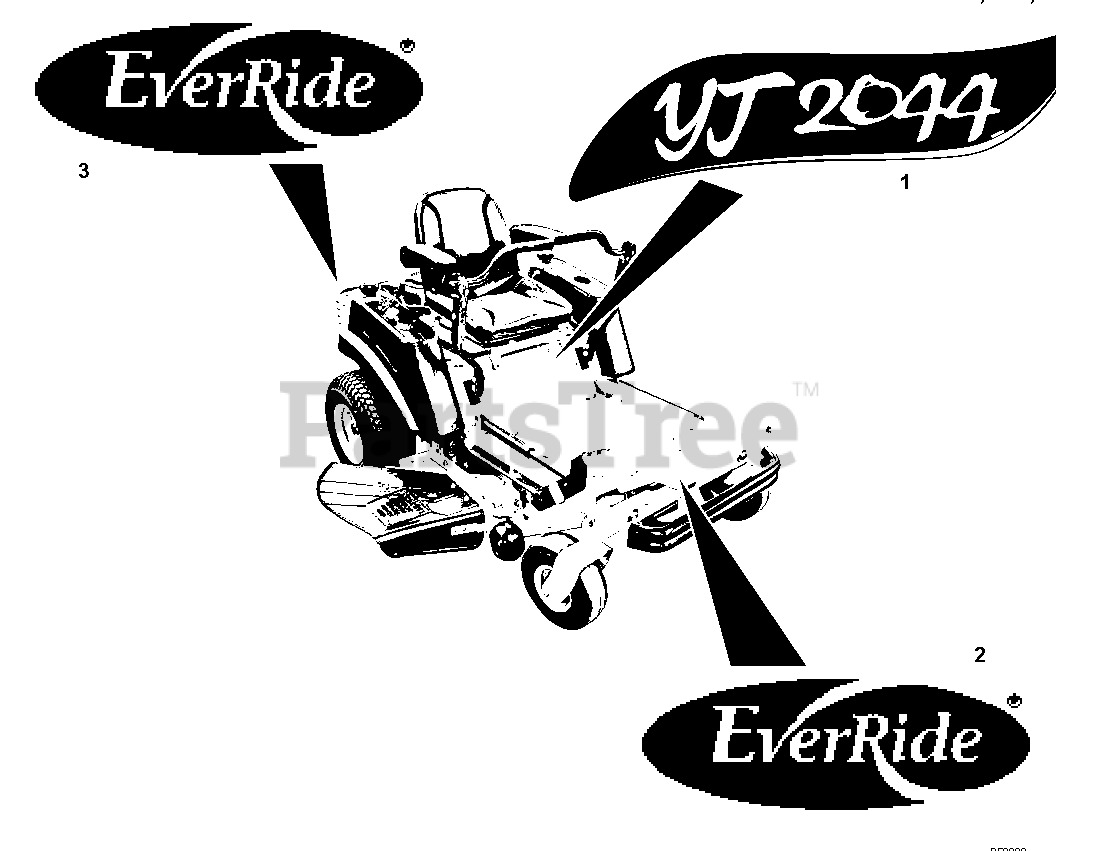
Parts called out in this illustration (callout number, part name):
1	Decal, YJ 1840 (400)
2	Decal, EverRide (Front)
3	Decal, EverRide (Rear)
